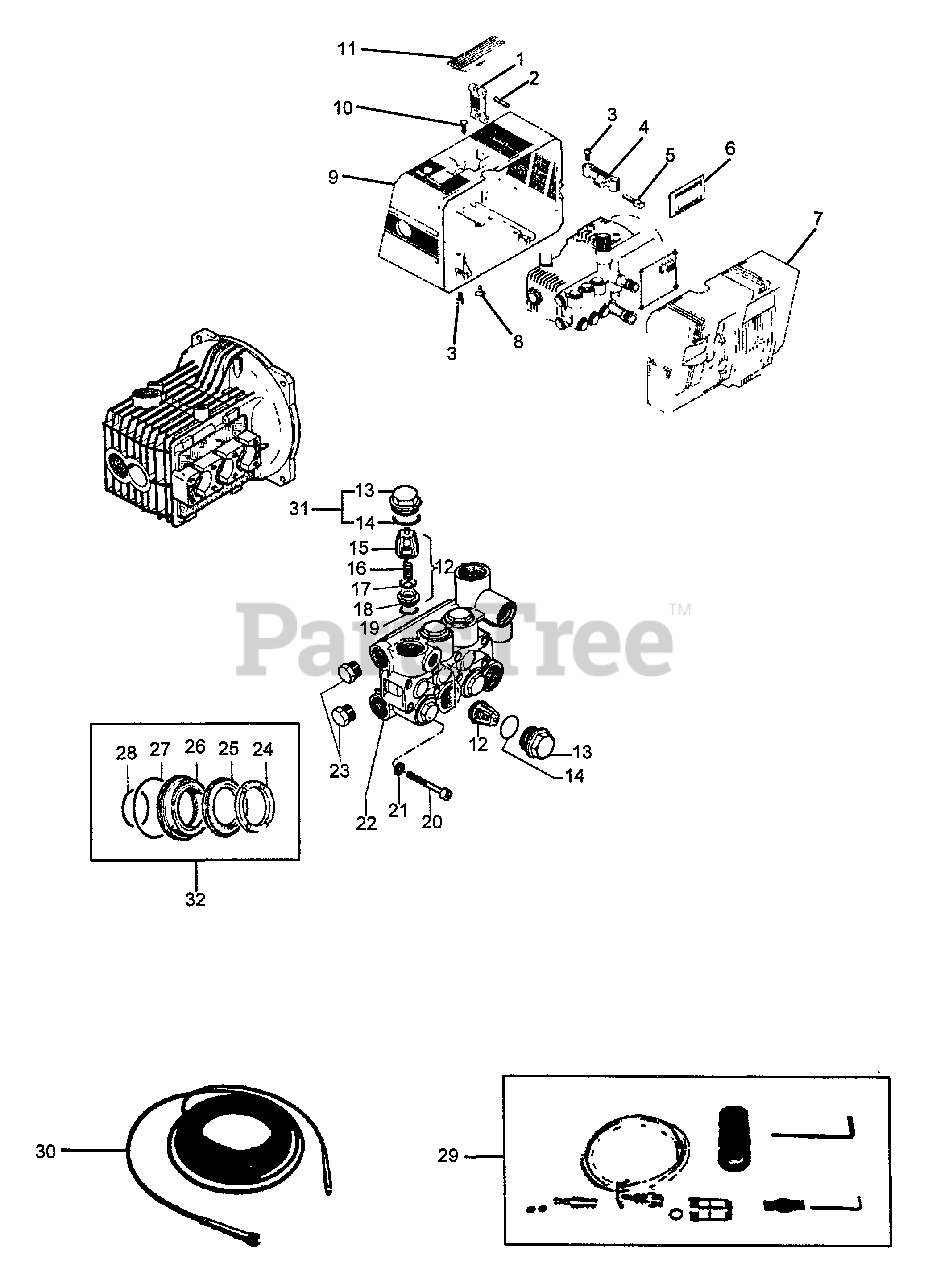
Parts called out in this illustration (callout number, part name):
1	ARM, HANDLE
2	PIN
3	SCREW M8×16
4	PLATE, HANDLE RETAINER
5	SHAFT
6	PLATE, ON-OFF
7	COVER, FRONT
8	PLUG
9	COVER, REAR
10	SCREW - 4×13
11	HANDLE
12	VALVE KIT
13	CAP
14	O-RING 0.797×.103
15	GUIDE, VALVE
16	SPRING
17	PLATE, VALVE
18	SEAT, VALVE
20	SCREW M6×40
21	LOCKWASHER - 6
22	MANIFOLD
23	CAP
24	RING, HEAD
25	PACKING
26	RETAINING, PACKING
27	O-RING
28	O-RING
29	ACCESSORY KIT
30	HOSE - 8M
31	VALVE KIT
32	SEAL KIT
